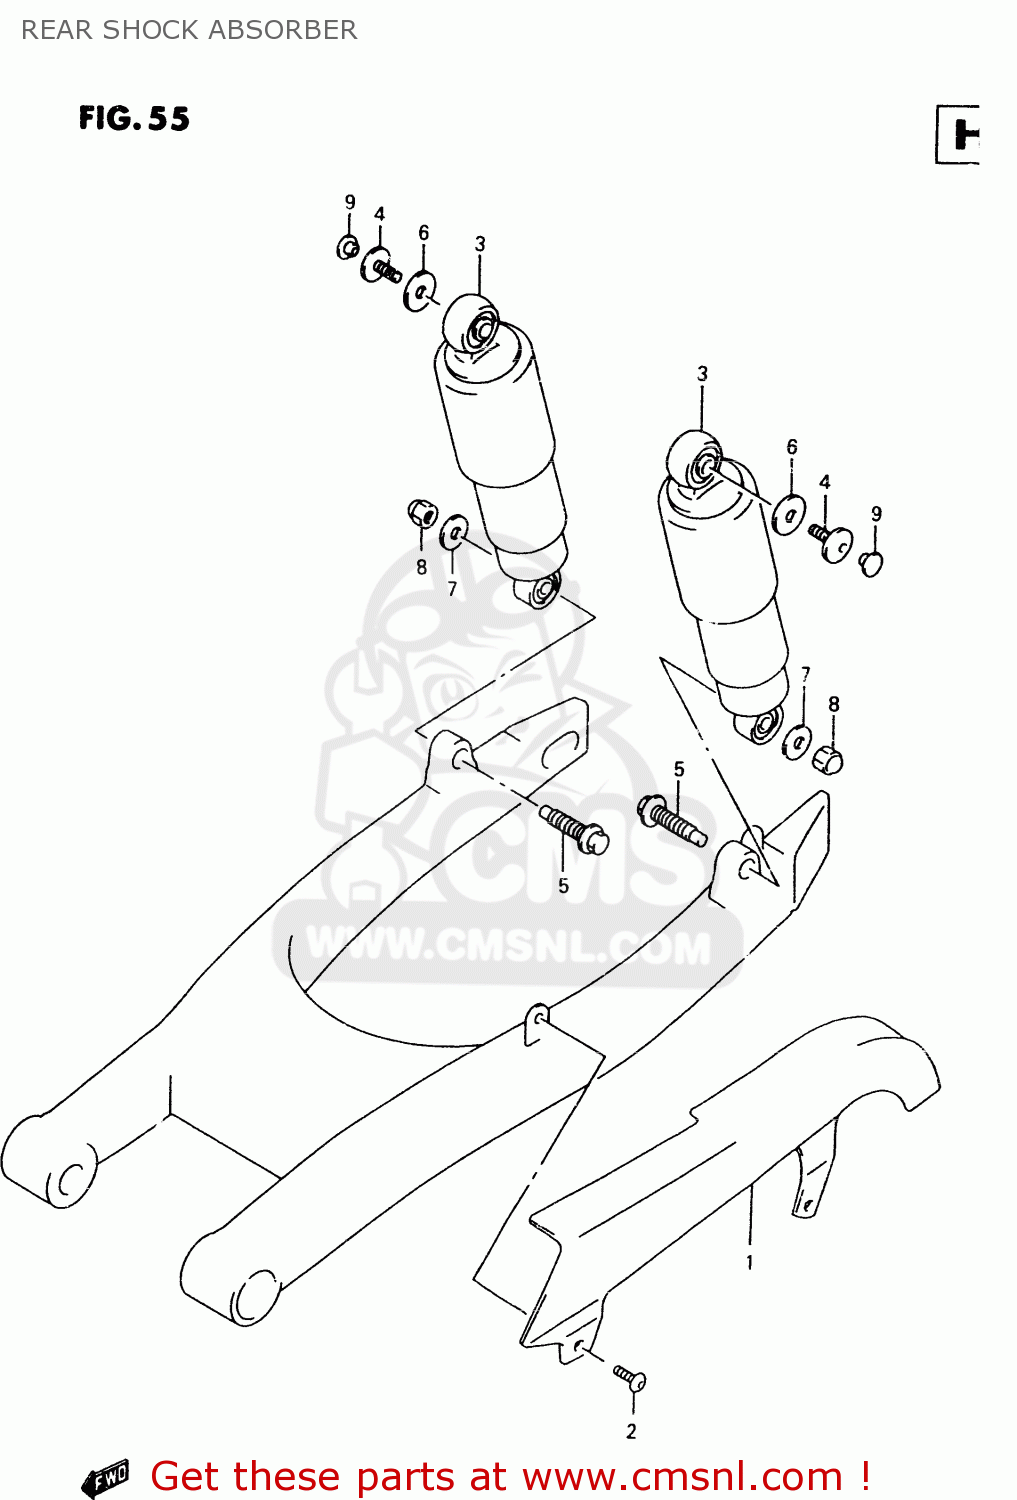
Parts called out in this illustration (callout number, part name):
1	CASE,CHAIN
2	SCREW
3	ABSORBER ASSY,RR SHOCK
4	BOLT(8X20)
5	BOLT,RR SHOCK ABSORBER
6	WASHER (8.5X30X2.3)
7	WASHER(10.5X28X2.3)
8	NUT
9	CAP(OD:14.5)
